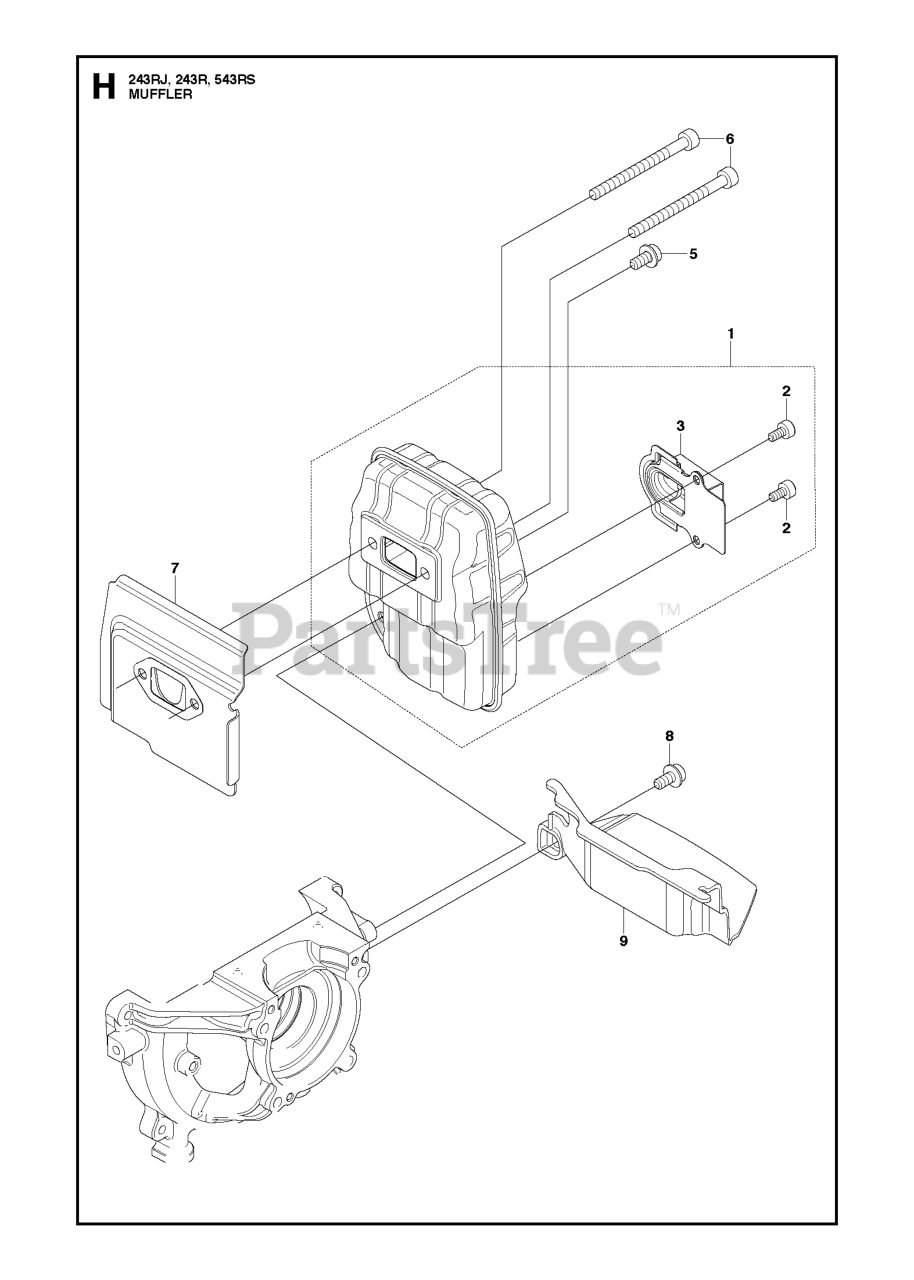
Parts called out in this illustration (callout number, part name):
1	MUFFLER-A
1	MUFFLER ASSY
2	BOLT
3	GUIDE
6	BOLT (RPLS T495051010-11)
6	BOLT
